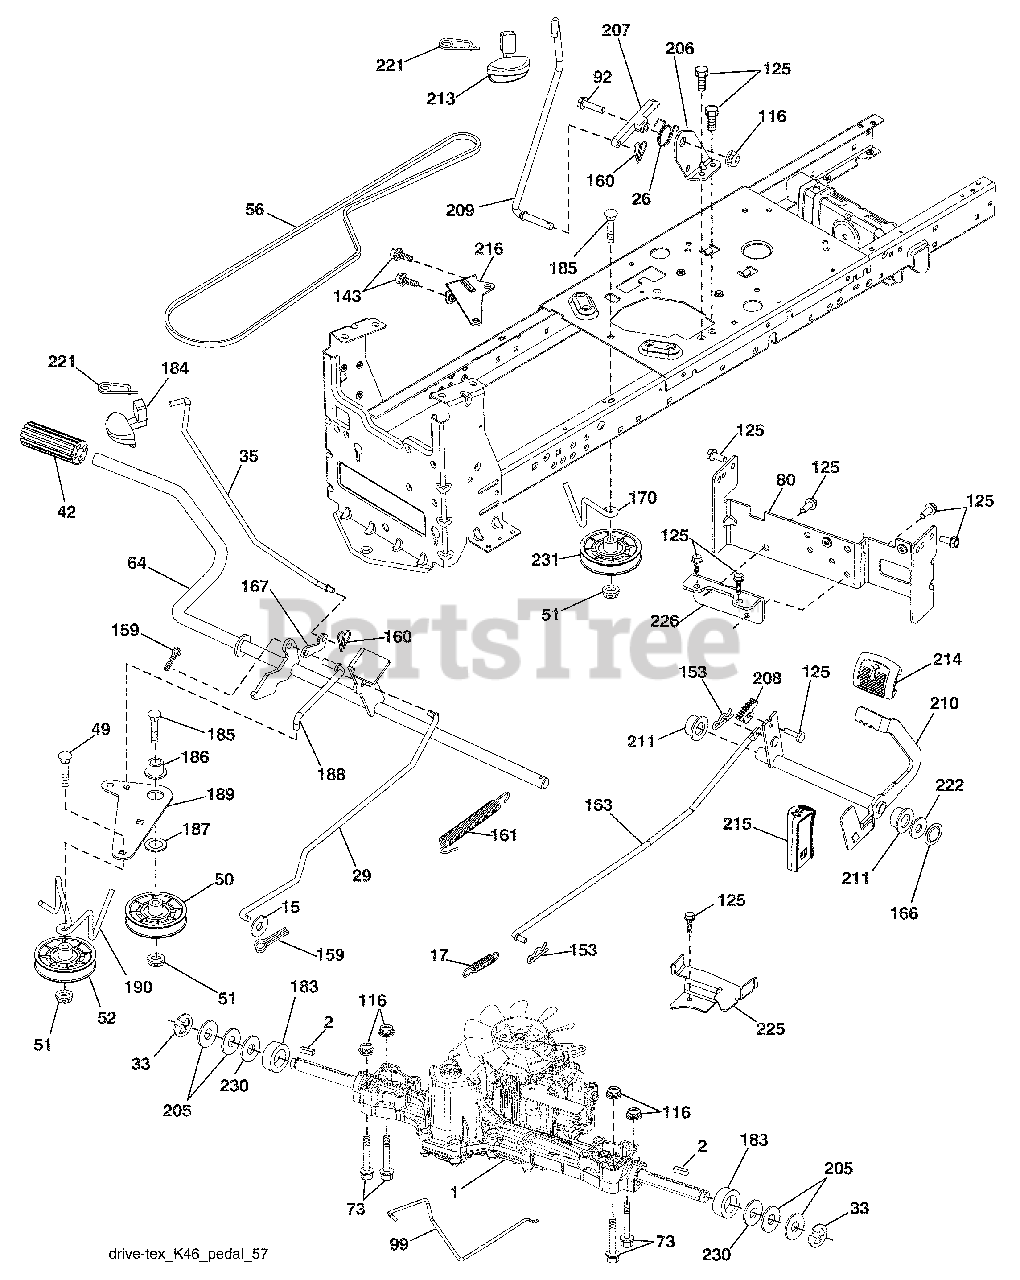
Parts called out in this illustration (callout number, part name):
1	Transaxle, TUFFTORQ K46 BT
15	Washer 13/32 x 13/16 x 16 Ga.
17	Spring, Brake
26	Spring Return Cruise
29	Rod, Brake
35	Rod, Brake, Park
42	Cover, Foot Pedal
50	Pulley Idler Flat
51	Lock Nut 3/8-16
52	Idler V-Groove 910" Offset
56	V-Belt, Drive
64	Shaft Asm. Pedal Brake Control
73	Bolt Hex Flghd 5/16-18 Gr. 5
80	Bracket Strap Torque
92	Bolt Fin Hex 5/16-18 unc x 1.25
99	Rod Asm. Bypass
116	Nut Lock Hex Flange 5/16-18
125	Screw 5/16-18 x 3/4
143	Screw 5/16-18 x 1/2
153	Retainer Spring
159	Pin Cotter 1/8 x 3/4
160	Retainer Clip
161	Spring, Return, Clutch
163	Rod Pedal Control
166	Nut Push
167	Latch Brake Parking
170	Keeper Belt Centerspan
183	Spacer Split
184	Handle Parking Brake
185	Bolt Rdhd Sqnk 3/8-16 x 2-3/4 Gr. 5
186	Spacer Retainer
187	Washer
188	Link Clutch Ground Drive
189	Bellcrank Ground Drive
190	Keeper Bellcrank Ground Drive
206	Bracket Mount Latch Cruise
207	Latch Control Cruise
208	Gear Sector Control Cruise
209	Rod Control Cruise
210	Rocker Asm. Pedal Control
211	Bearing Nylon
213	Knob Control Cruise
214	Pedal Forward
215	Pedal Reverse
216	Bracket Pulley Idler
221	Retainer Spring Clip Handle
222	Washer 21/32 x 1-1/4 x 10 Ga.
225	Keeper Belt Trans.
226	Bracket Mount Torque
230	Washer Hardened
231	Idler V-Groove 1.688" Offset
